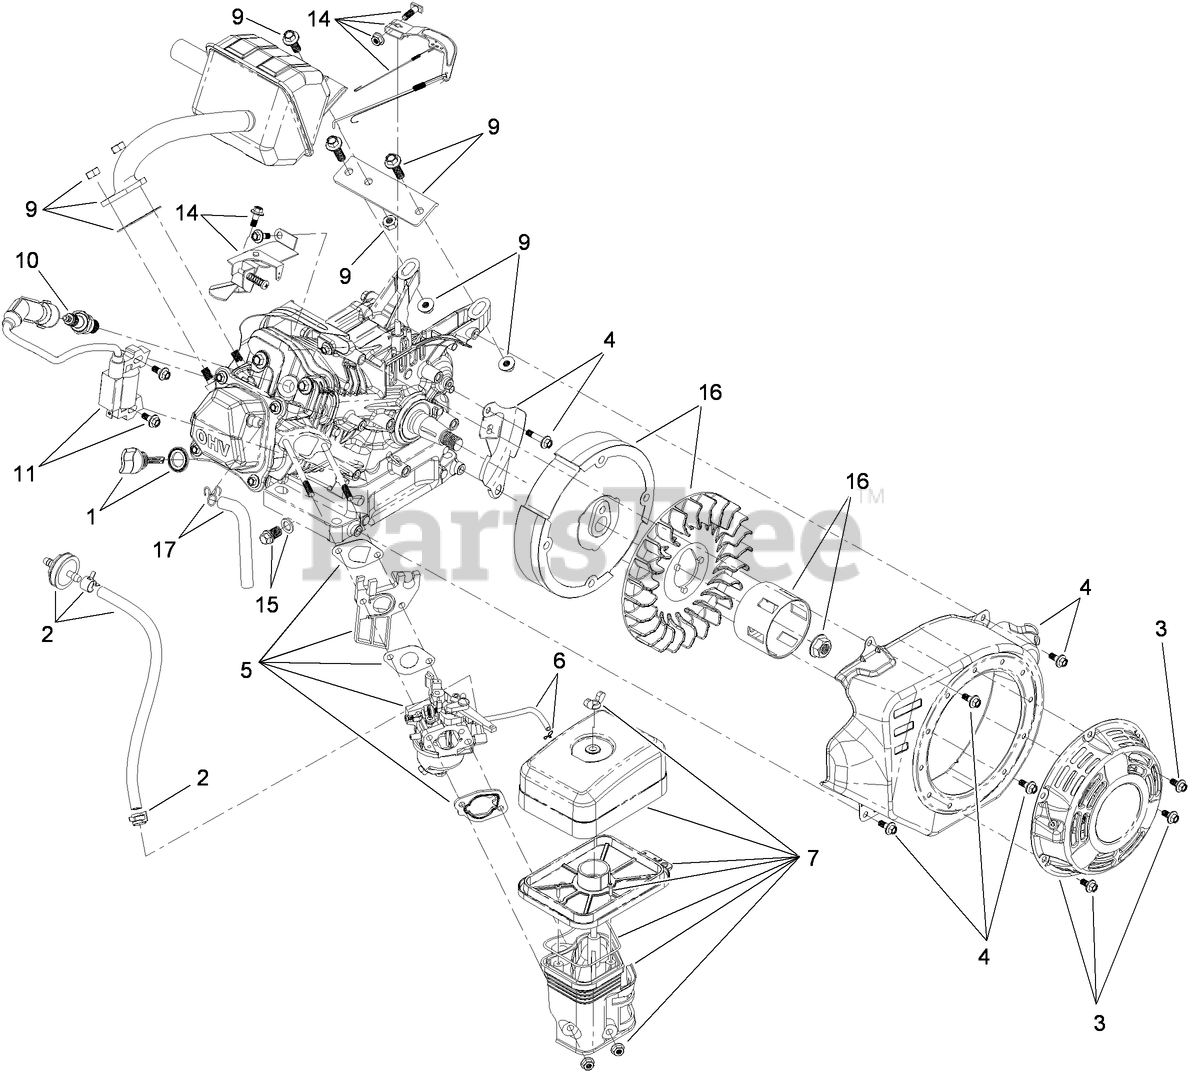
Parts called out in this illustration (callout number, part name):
4	BLOWER SHROUD KIT
5	COMPLETE CARBURETOR SERVICE KIT
5	CARB AND FUEL LINE KIT
9	MUFFLER KIT
14	GOVERNOR KIT
15	DRAIN PLUG KIT
16	FLYWHEEL KIT
17	BREATHER TUBE KIT
